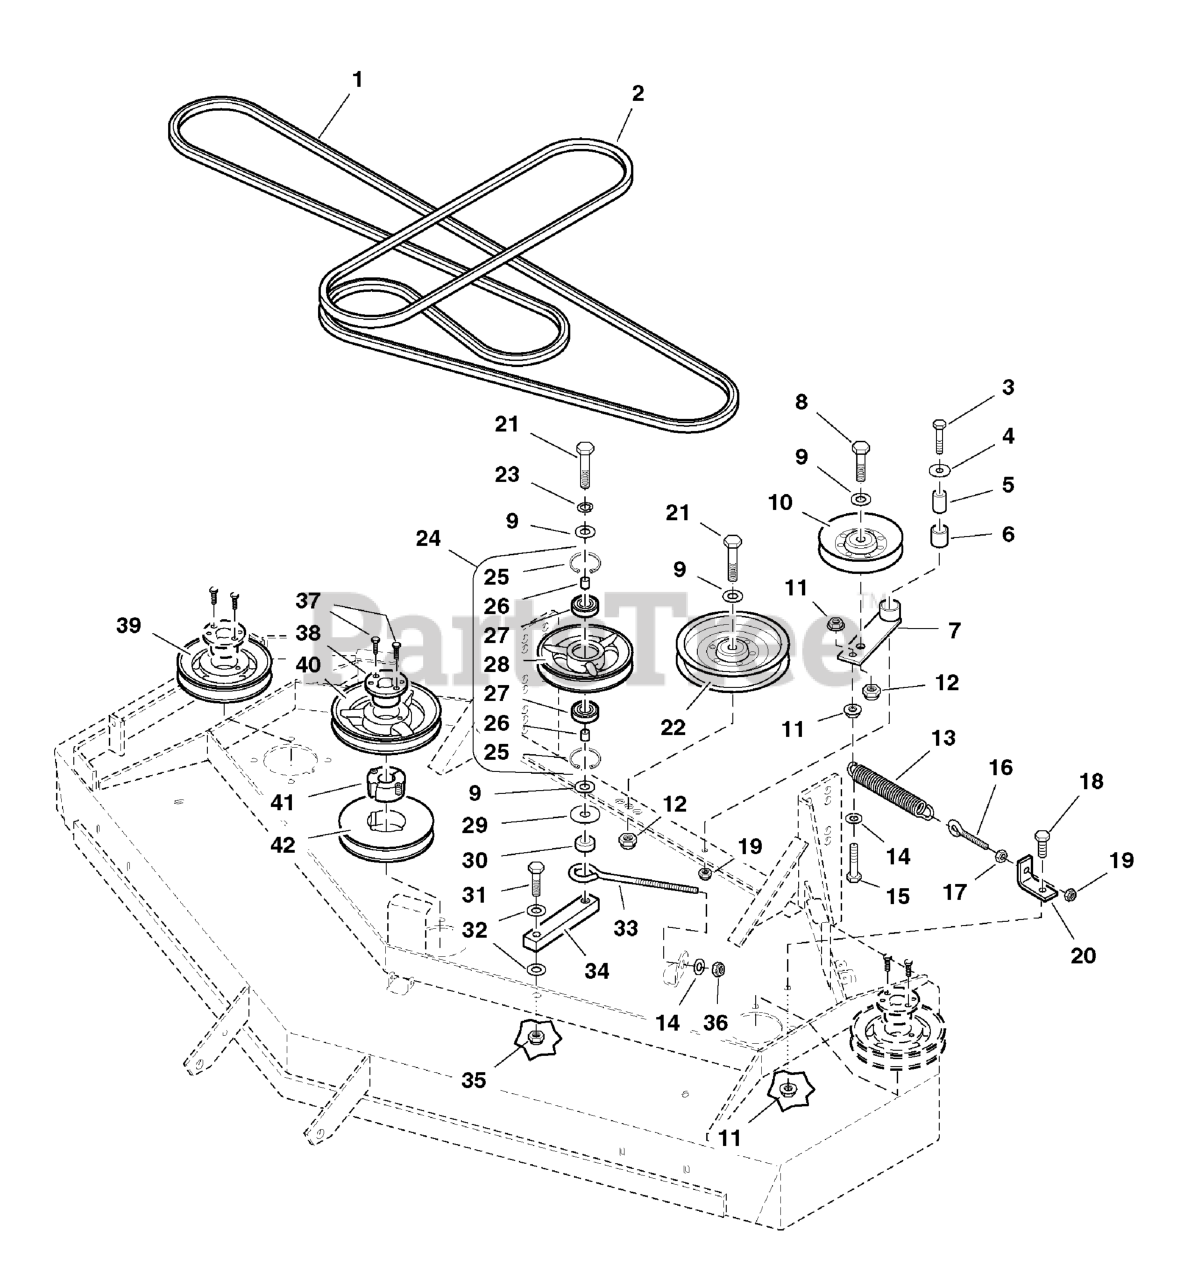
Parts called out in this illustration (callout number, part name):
1	BELT, Blade Spindle
2	BELT, Deck Drive
3	BOLT, 5/16-18 x 1-3/4
4	WASHER, 5/16" Fender
5	SPACER, .32 x .75 x 1.06
6	BUSHING, Brass
7	IDLER ARM, Complete
8	BOLT, 1/2-20 x 2
9	WASHER, 1/2 SAE
10	PULLEY, V-Idler
11	NUT, 3/8-16 Hex Serrated Flange
12	NUT, Hex, Nylon Lock, 1/2-20
13	SPRING, Extension
14	WASHER, 3/8 SAE
15	BOLT, 3/8-16 X 2, GD5, CZ
16	EYE BOLT,5/16-18 X3.5,2.13THRD,.55EYE,CZ
17	NUT, 5/16-18 HEX
18	BOLT, 3/8-16 X 1" GD5 CZ
19	NUT, 5/16-18 Hex Nylon Lock
20	SPRING ANCHOR
21	BOLT, 1/2-20 X 2-1/4 GD5 CZ
22	PULLEY, Backside Idler
23	WASHER, 1/2" Lock
24	IDLER PULLEY, Complete
25	SNAP RING, Internal
26	INSERT, Bearing
27	BEARING, BALL 11/16X1-9/16X15/32
28	PULLEY, Idler
29	WASHER, 1/2" USS
30	SPACER, .52 X 1.00 X .38
31	BOLT, 7/16-20 X 1-3/4" GD.5
32	WASHER, 7/16" SAE
33	EYEBOLT, 3/8" x 8"
34	ARM, Idler
35	NUT, 7/16-20 Hex Nylon Lock
36	NUT, 3/8-16 HEX NYLON LOCK
37	BOLT, 1/4-20 X 1" GD5 CZ
38	BUSHING, Tapered Hub
39	PULLEY, Spindle
40	PULLEY, Spindle
41	BUSHING, Taper Lock
42	PULLEY, Taper Lock
